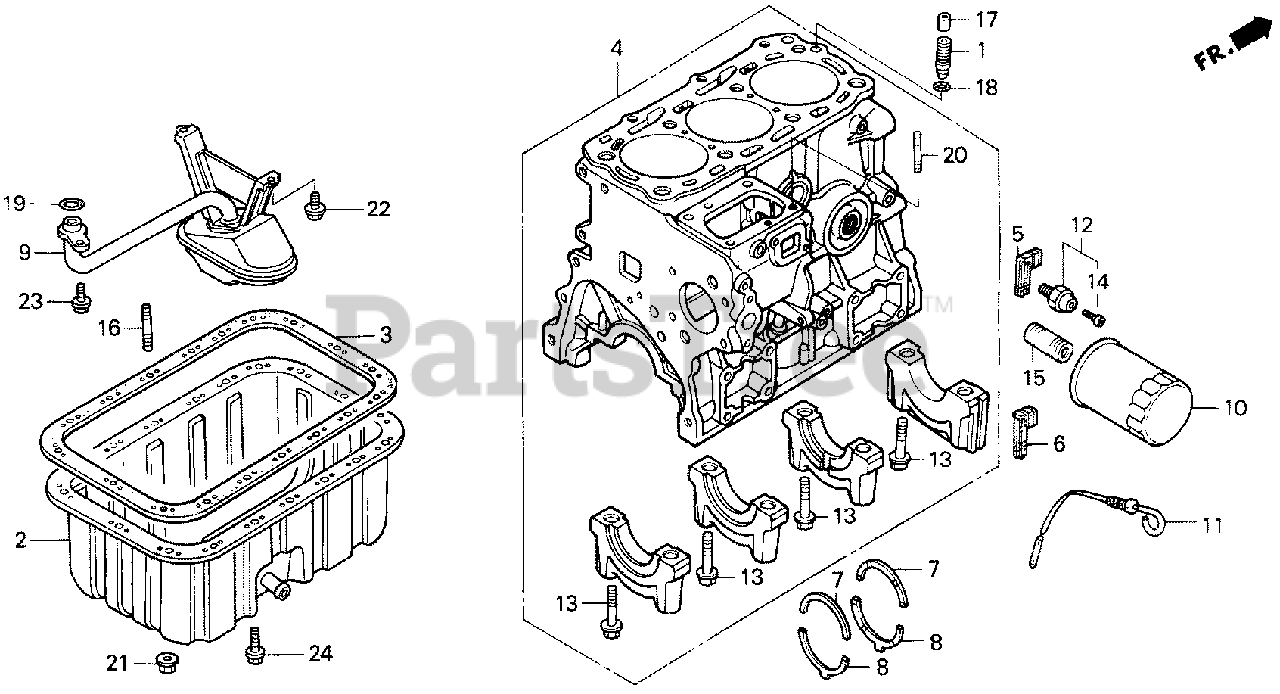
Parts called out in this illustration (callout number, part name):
1	ORIFICE, OIL CONTROL
3	GASKET, OIL PAN
4	BLOCK ASSY., CYLINDER
5	RUBBER, R. SIDE SEAL
6	RUBBER, L. SIDE SEAL
7	BEARING A, CRANKSHAFT THRUST
8	BEARING B, CRANKSHAFT THRUST
9	STRAINER, OIL
10	FILTER, OIL (SOLD INDIVIDUALLY)
11	DIPSTICK, OIL
12	SWITCH, OIL PRESSURE
13	BOLT, FLANGE (11X69)
14	SCREW-WASHER (4X8)
15	HOLDER, OIL FILTER
16	BOLT, STUD (6X28)
17	PIN, DOWEL (14X16)
18	O-RING (6.5X1.5)
19	O-RING (17.0X2.5) (ARAI)
20	BOLT 2, STUD (8X22)
21	NUT, FLANGE (6MM)
22	BOLT, FLANGE (6X10)
23	BOLT, FLANGE (6X16)
24	BOLT, FLANGE (6X18)
